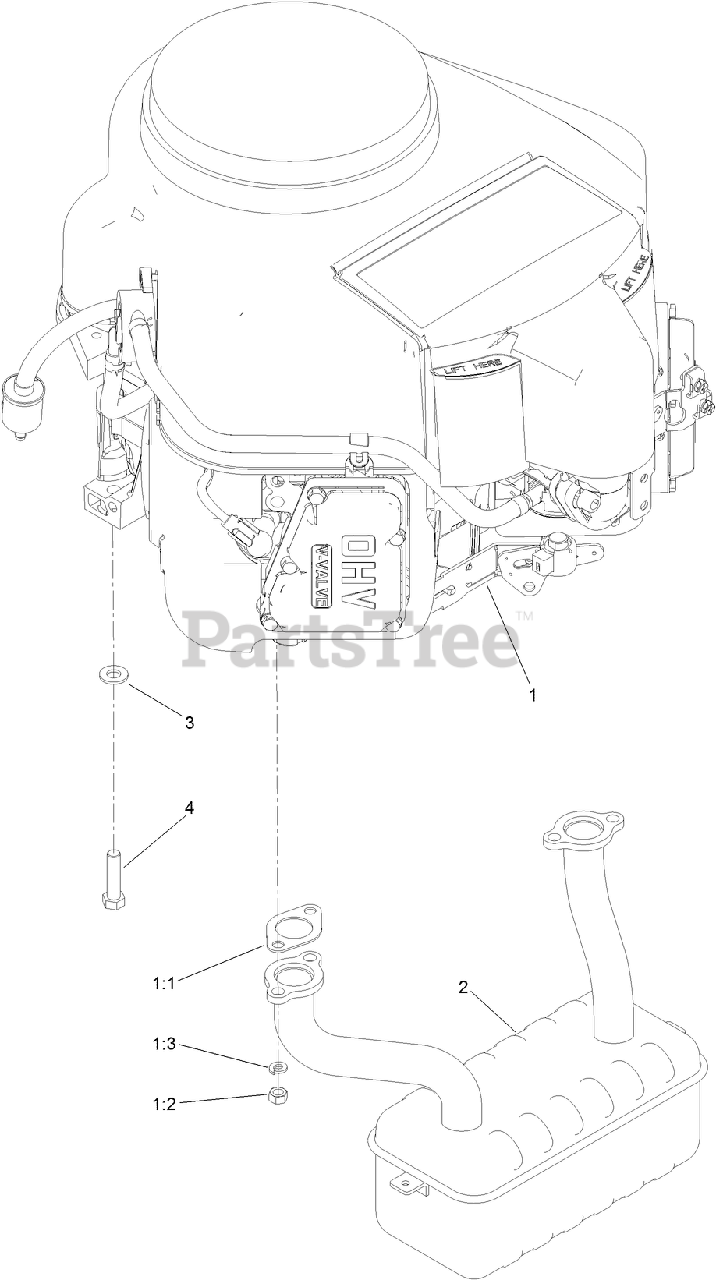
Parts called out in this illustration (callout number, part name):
1:1	GASKET-EXHAUST
1:3	WASHER-LOCK
2	MUFFLER
3	WASHER-FLAT
4	BOLT-HH
